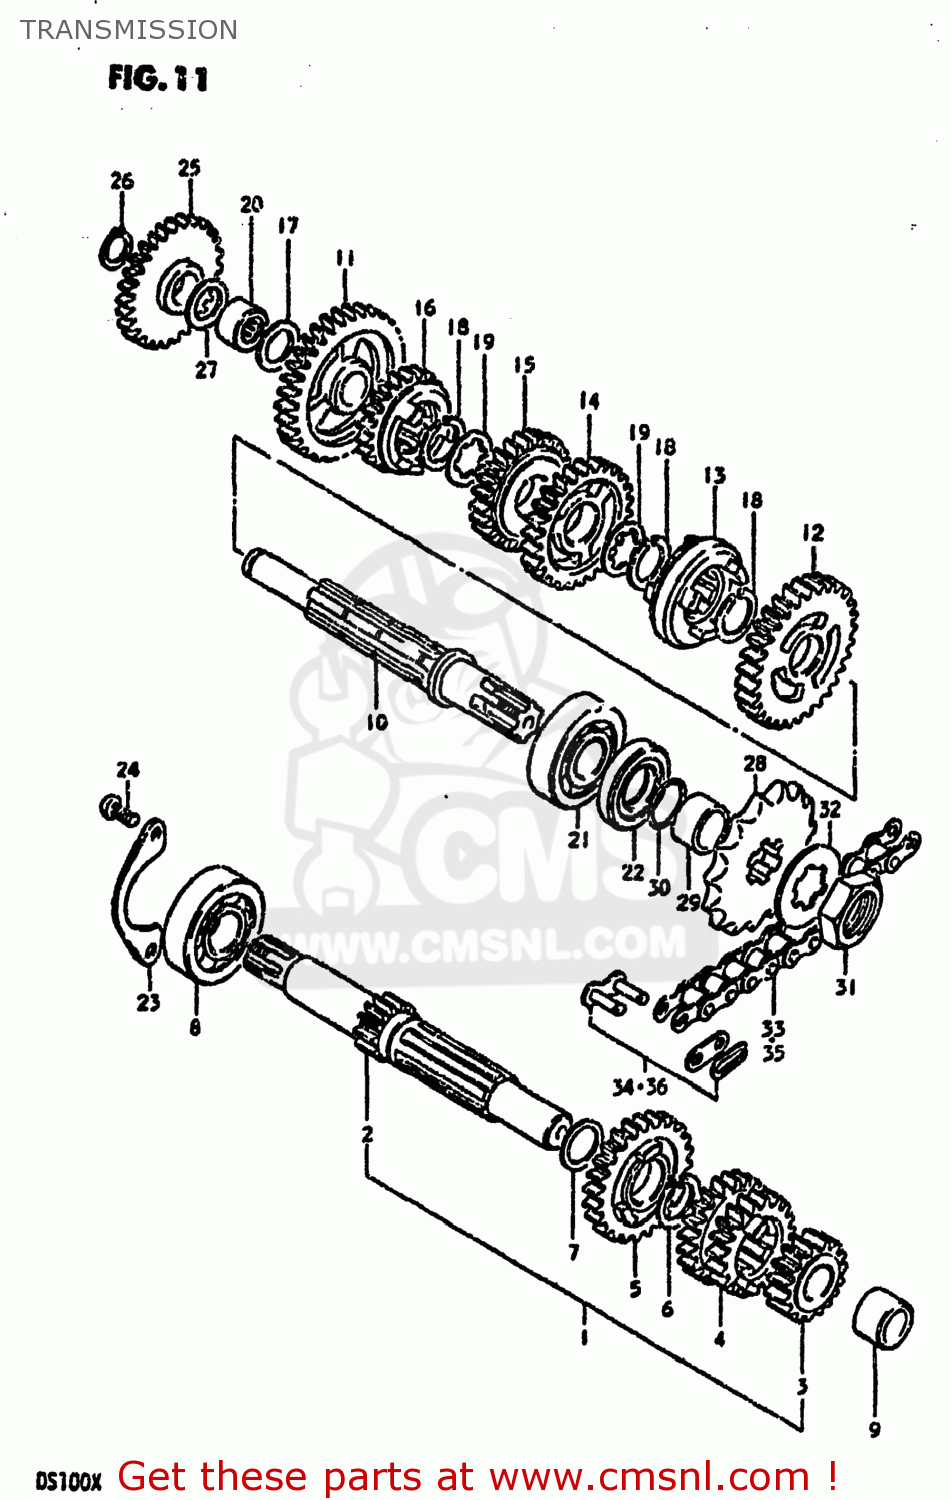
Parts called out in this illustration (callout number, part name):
1	SHAFT ASSEMBLY,COUNTER
2	SHAFT,COUNTER
3	GEAR,SECOND DRIVE
4	GEAR,THIRD/FOURTH DRIVE
5	GEAR,FIFTH DRIVE
6	CIRCLIP
7	WASHER
8	Bearing
9	BUSH(15X22X15)
10	SHAFT,GEAR SHIFT
11	GEAR,1ST DRIVEN
12	GEAR,SECOND DRIVEN
13	WHEEL,SECOND DRIVEN GEAR
14	GEAR,THIRD DRIVEN
15	GEAR,FOURTH DRIVEN
16	GEAR,FIFTH DRIVEN
17	WASHER,THRUST
18	CIRCLIP
19	WASHER,LOCK
20	BEARING(15X22X12)
21	Bearing
22	SEAL,OIL(25X40X7)
23	RETAINER,CNTR SHAFT BEARING
24	SCREW 6X12
25	GEAR,KICK STARTER IDLE
26	CIRCLIP,15MM
27	WASHER,THRUST
28	SPROCKET,ENGINE
29	SPACER(20X25X12.5)
30	O RING(D:1,ID:19.5)
31	NUT
32	WASHER,LOCK
33	CHAIN ASSEMBLY,DRIVE
34	JOINT ASSEMBLY,CHAIN
35	CHAIN ASSEMBLY,DRIVE
36	JOINT ASSEMBLY,CHAIN
